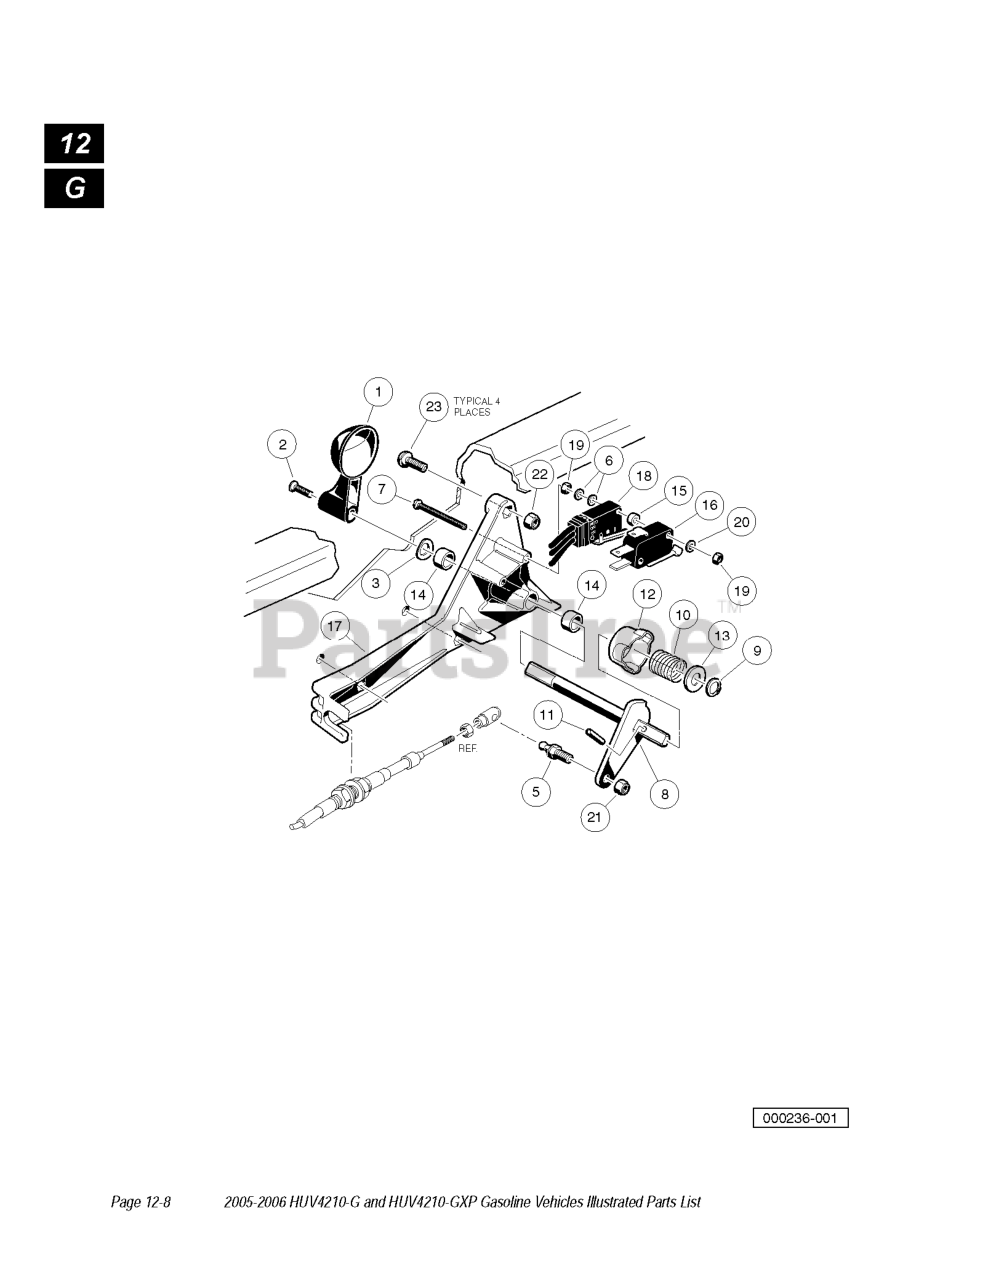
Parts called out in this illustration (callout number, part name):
1	HANDLE, FNR SWITCH
3	WASHER, WAVE
4	F & R SHIFTER ASSEMBLY
8	F&R BELL CRANK WELDMENT
10	SPRING, FNR CAM
12	NEUTRAL LOCKOUT CAM KIT
14	BUSHING, SECONDARY WGHT SPLIT
16	SWITCH, LIMIT
17	SHIFTER BASE
18	SWITCH ASSY, SEALED LIMITER
19	NUT HEX MACHINE
20	LOCKWASH, # 4 HELICAL SPLIT
21	LOCKNUT, 1/4-28 NYLON INSERT
22	LOCKNUT, 1/4-20 NYLON INSERT
23	SCREW 1/4-20 X .75
